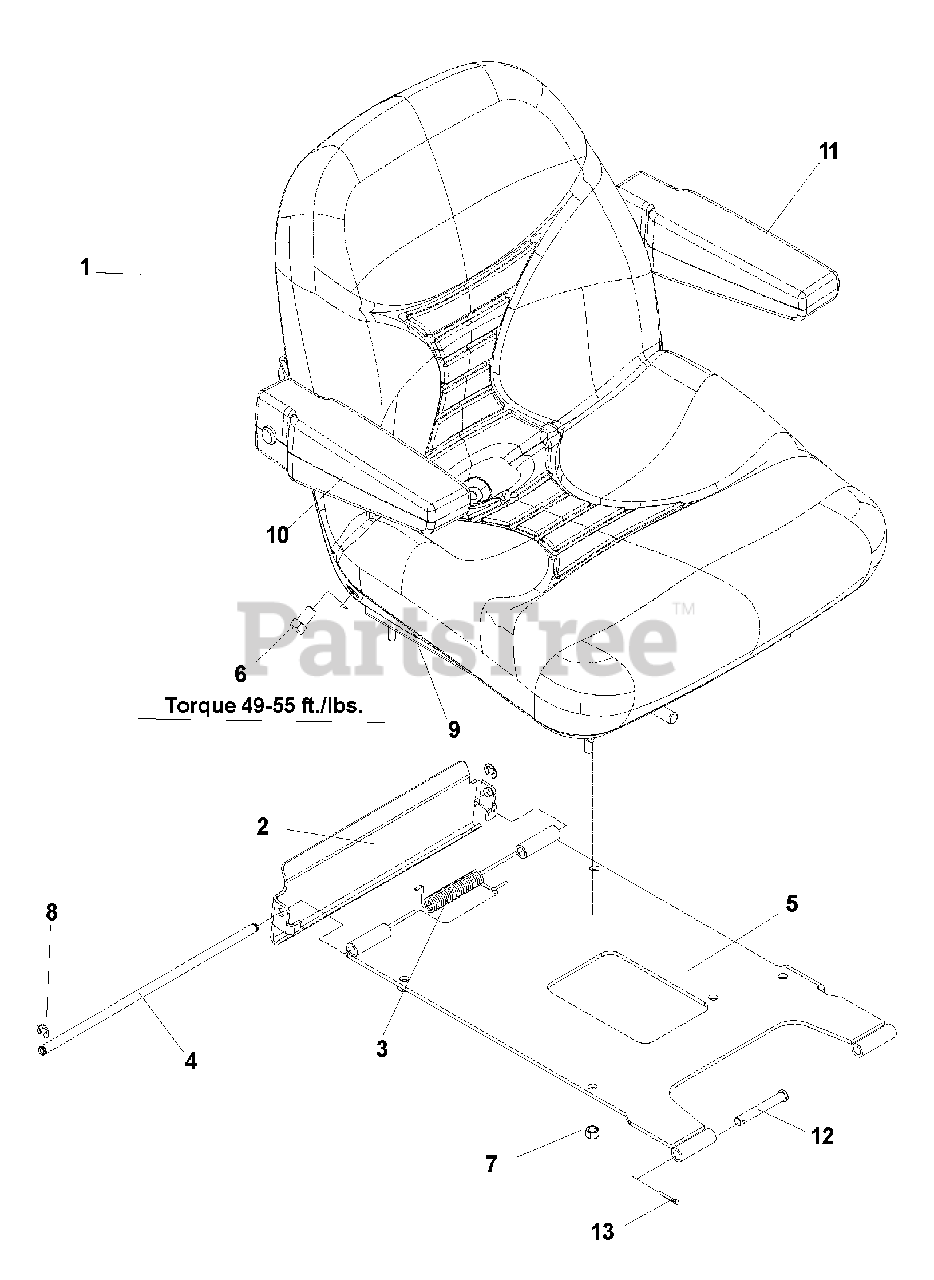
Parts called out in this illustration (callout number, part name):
1	SEAT, STANDARD
2	SEAT LATCH BRACKET
3	TORISON SPRING
4	SEAT LATCH ROD
5	SEAT MOUNT
6	HCS, 7/16-20 X 3/4, GR5
7	NUT, 5/16-18, NYLOC
8	RING-RETAINING
9	TRACK ADJUSTMENT KIT
10	ARM REST KIT, RIGHT
11	ARM REST KIT, LEFT
12	CLEVIS PIN
13	PIN, COTTER, 1/8 X 3/4
